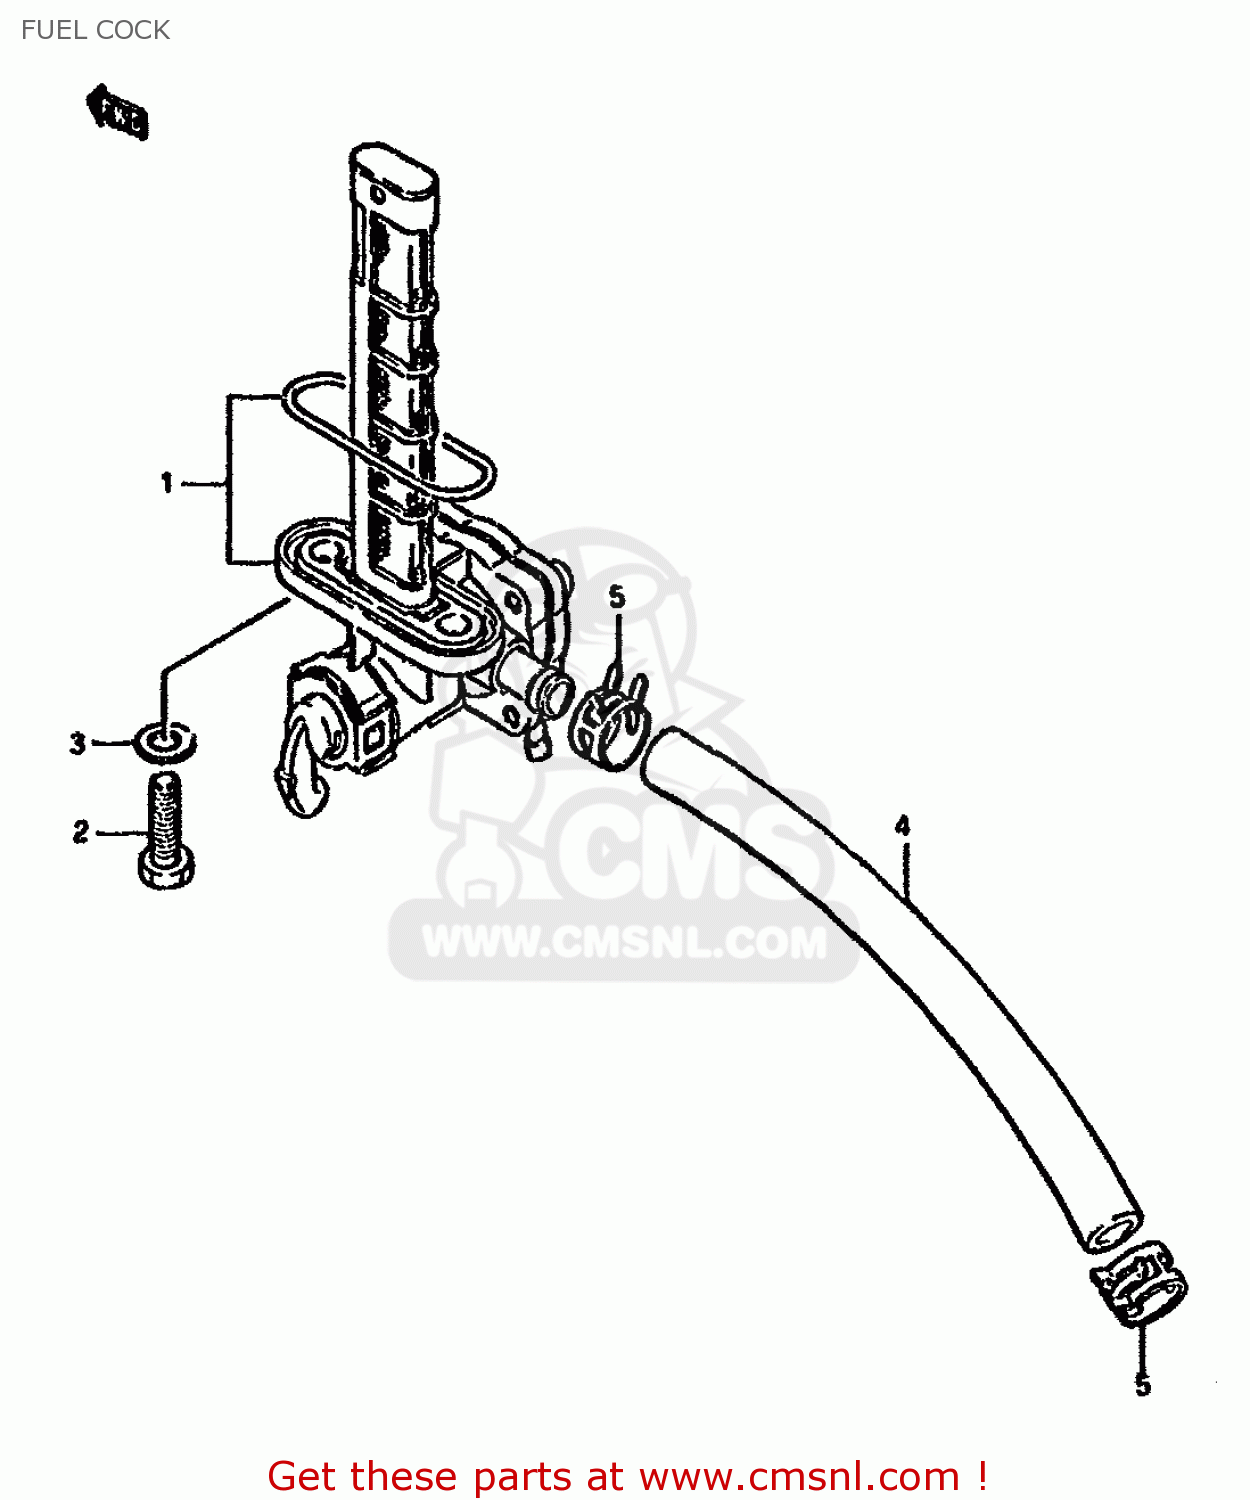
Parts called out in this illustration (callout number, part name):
1	COCK ASSY,FUEL
2	BOLT(6X20)
3	GASKET(5.8X13X1.2) (NAS)
4	HOSE
5	CLAMP
